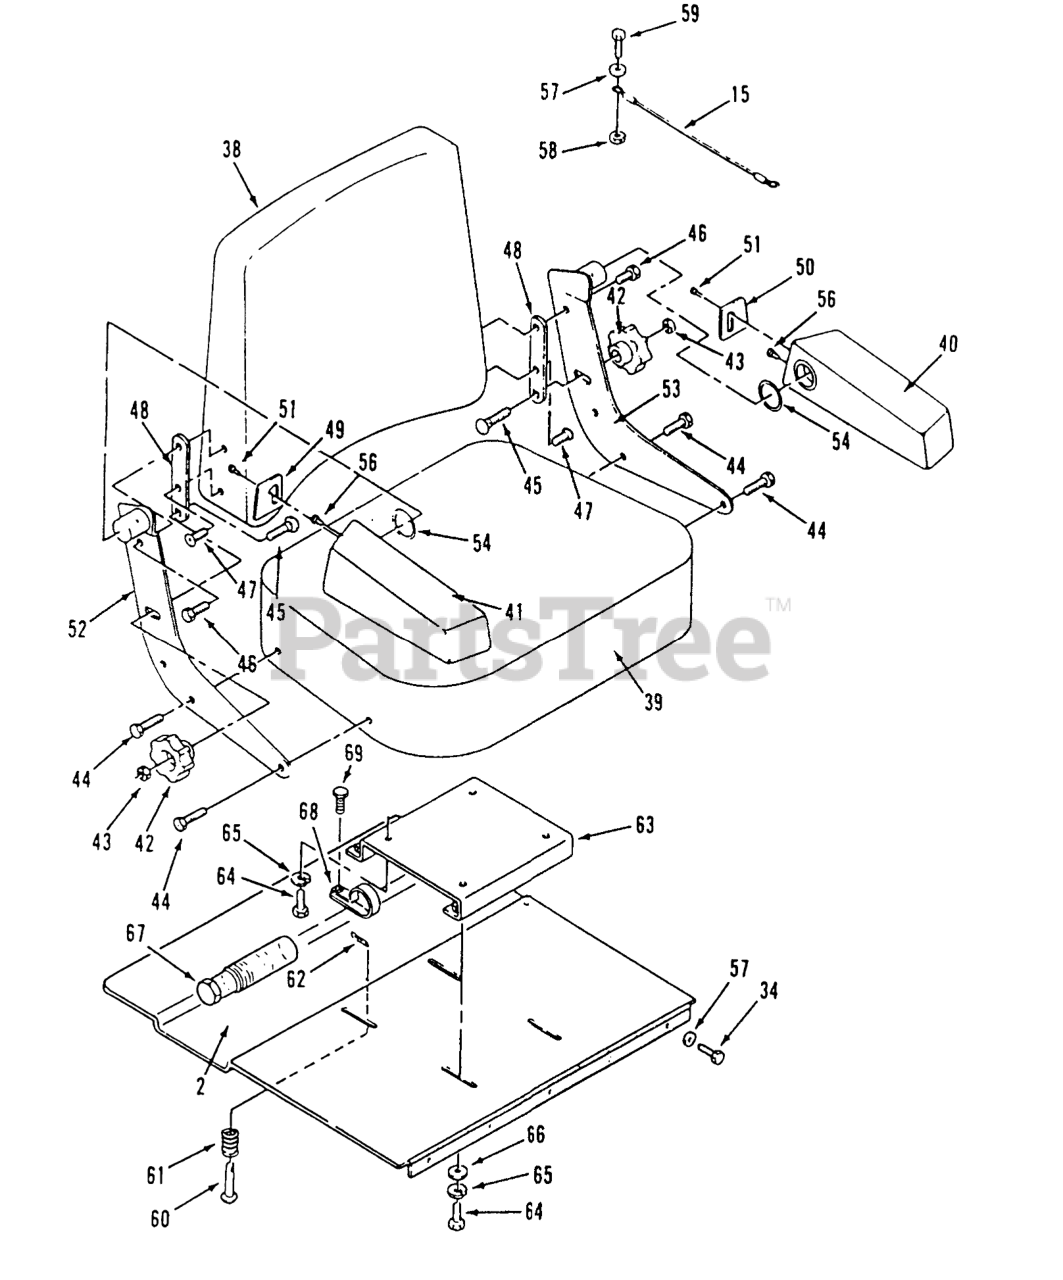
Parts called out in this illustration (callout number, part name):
2	WLDMT-SEAT BRKT B
15	Cable
34	SCREW-HWH
38	SEAT BACK
39	SEAT BOTTOM
40	ARM REST LH
41	ARM REST RH
42	Knob-Lumbar Control
43	KNOB, LUMBAR CONTROL
44	SCREW-HH
45	SCREW-CARR
46	SCREW-HH
47	FLAT HEAD MACH SCREW
48	FRICTION PLATE
49	ARM REST PLATE RH
50	ARM REST PLATE LH
51	SCREW PAN HD 10-16X5
52	RH BACK SUPPORT
53	BACK SUPT LH
54	WASHER
56	SHCS 1/4-20 X 1/2
57	WASHER-FLAT
58	NUT-LOCK, NI
59	SCREW-HH
61	SPRING-COMPRESSION
62	PIN-COTTER
63	ASS'Y-SUPPORT SEA B
64	SCREW-HH
65	WASHER-FLAT
66	WASHER-FLAT
67	TUBE-MANUAL
68	CLAMP-R
69	SCREW-TAPTITE
